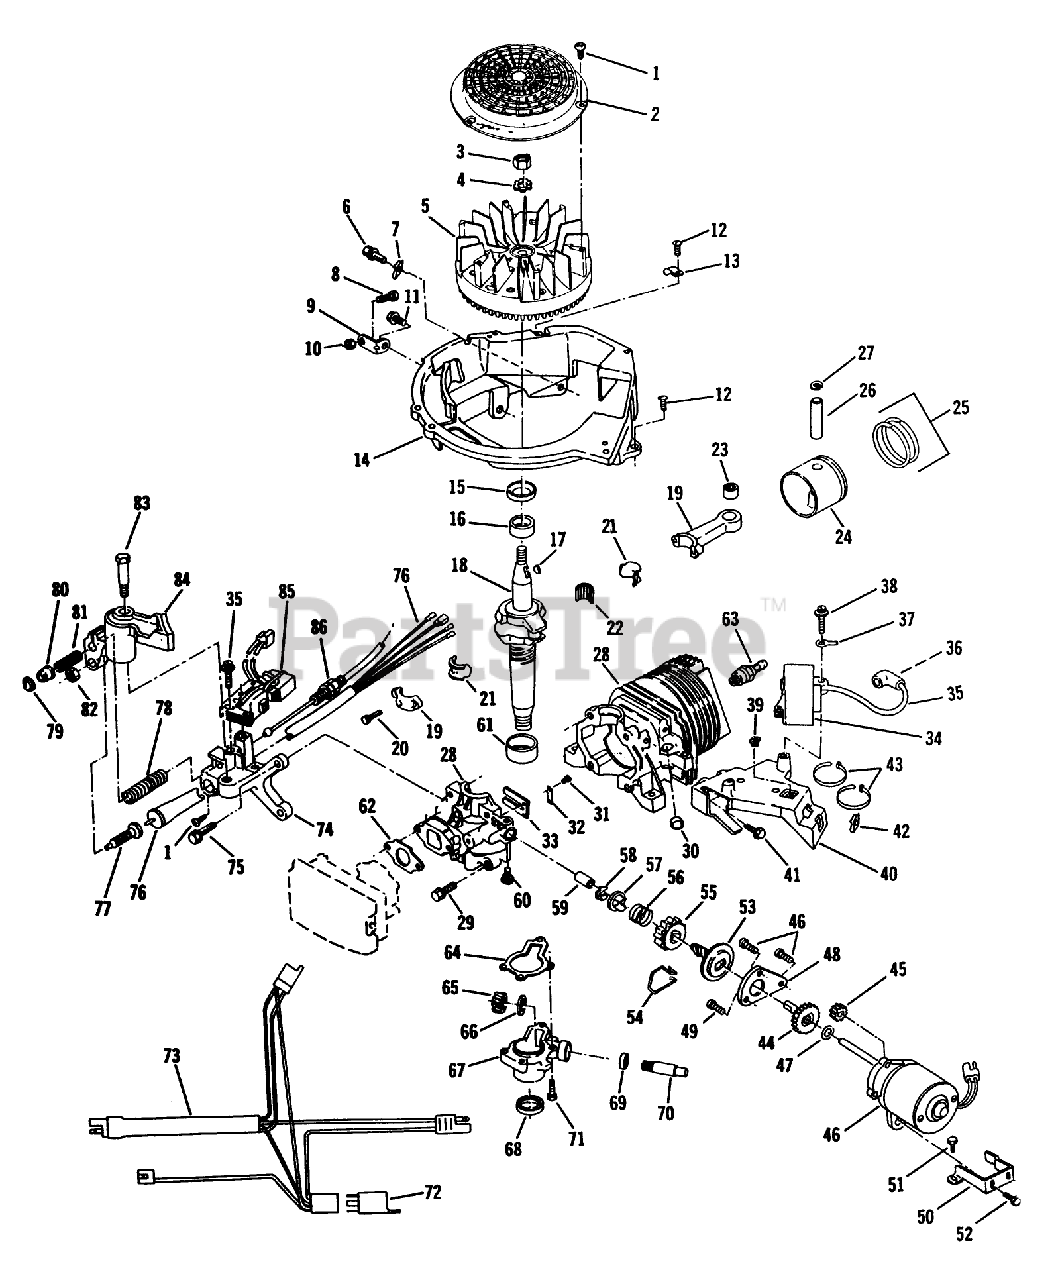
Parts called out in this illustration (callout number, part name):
1	SCREW F
2	SCREEN F'WHEEL S
3	NUT
6	SCREW-SEMS
8	BOLT F
10	NUT-LOCK F
12	SCREW F
14	BASE SHROUD F
16	BEARING V
17	KEY
20	SCREW-HSH
21	LINER ASM
23	BEARING AY F
27	RING-RETAINING
29	SCREW S
30	PLUG-CORE VF
32	PLATE-BACKUP, REED
35	HT LEAD&COVER XEV
37	TERMINAL S
39	NUT-CLIP
42	NUT - SPEED S
44	GEAR-DRIVEN
45	*PINION EF
49	SCREW EF
50	BRACKET
52	SCREW
54	SPRING F
55	PINION EF
56	*SPRING PINION EF
58	RET.RING EF
59	SLEEVE F
61	BEARING S
62	GASKET CARB S
64	GASKET S
65	GEAR, DR SHAFT S
66	THRUST WASHER
68	SEAL-OIL
69	SEAL S
74	BRACKET F
77	PLUNGER S
78	SPRING-BRAKE
79	RETAINER S
80	ACTUATOR-LEVER, BRAKE
81	SPRING
86	CONTROL CABLE
